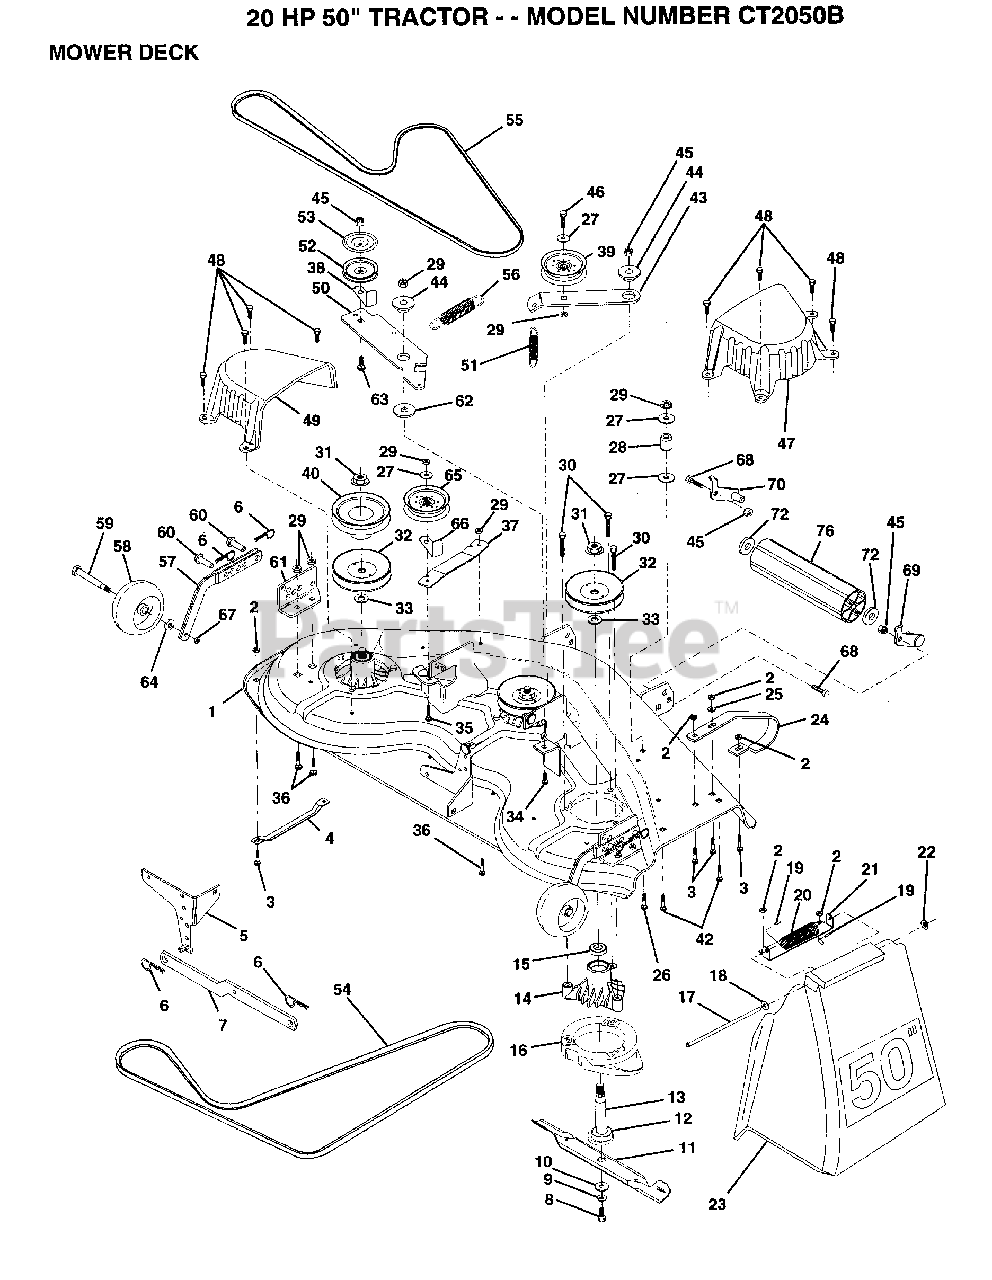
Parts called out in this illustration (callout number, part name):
1	DECK ASM MWR 50VT
2	NUT
4	RUNNER-LH M
5	BRKT.ASM.SW.44/50
8	BLADE BOLT
10	WASHER.HARD.BLADE
11	"BLADE.50"" HD"
12	BEARING.BALL
13	SHAFT.ASM.W/BRNG
14	HOUSING.MAND.44.V
15	BEARING
17	ROD-HINGE T
18	WASHER
19	CAP-SLEEVE LT
20	SPRING TORSION
21	BRKT DEFLECTOR
22	NUT PUSH M
23	DEFLECTOR
24	"RUNNER RH 50"" DK"
25	WASHER M
26	BOLT
27	WASHER
29	NUT
33	WASHER
34	BOLT.3/8-14X1.25
35	BOLT
36	BOLT D
37	STIFFENER.ARM.IDL
39	FLAT IDLER PULLEY
40	"PULLEY.DRIVEN.44"""
42	BOLT
43	"ARM.IDLER.SEC.44"""
44	SPACER RETAINER
47	"COVER.MAND.RH.44"""
48	SCREW.1/4-20X5/8
49	COVER.MANDREL.LH
50	ARM.IDLER.PRIMARY
51	"SPRING.SEC.44""VEN"
52	PULLEY.IDLER.VGRO
53	SHIELD.IDLER.44.V
54	BELT V PRIM 50
55	BELT.V.GDRIVE.95
56	SPRING.EXT.DECK.
57	BAR.ASM.GUAGE.WHL
58	WHEEL.GAGE.BLK.PL
59	BOLT M
60	PIN.CLEVIS
61	BRACKET.GUAGE.WHL
62	HARDENED WASHER
63	BOLT.3/8-16X1.50
64	WASHER
65	IDLER-FLAT T
67	LOCKNUT
68	BOLT
71	WASHER
72	WASHER
